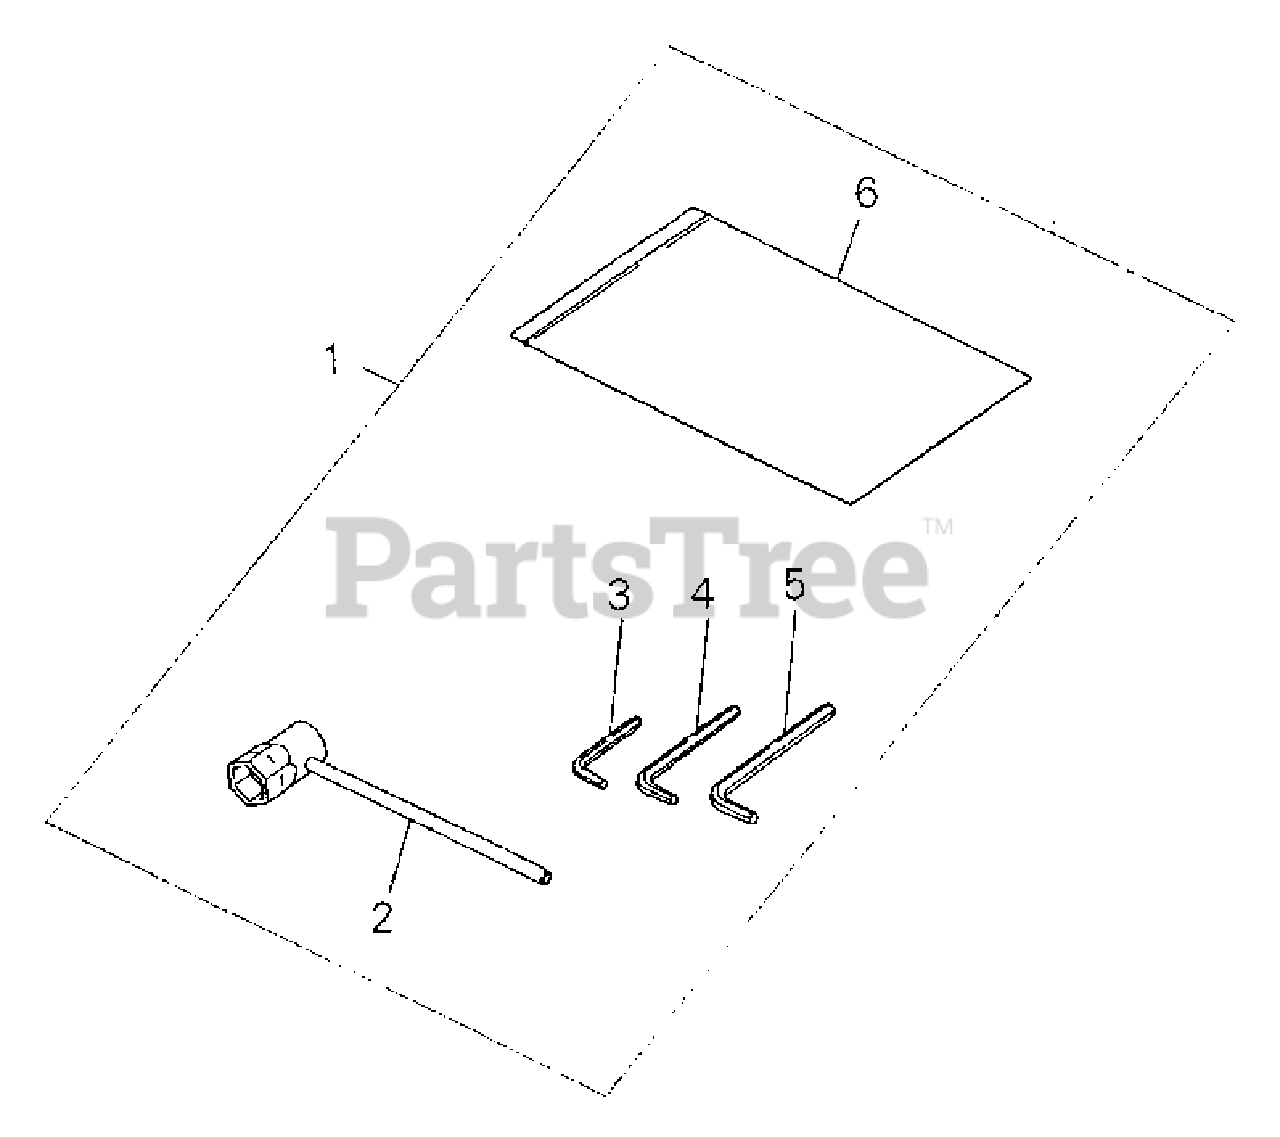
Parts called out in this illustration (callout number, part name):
1	TOOL KIT
2	SOCKET WRENCH
3	HEX KEY - 3mm
4	HEX KEY - 4mm
5	HEX KEY - 6mm
6	BAG, TOOL
